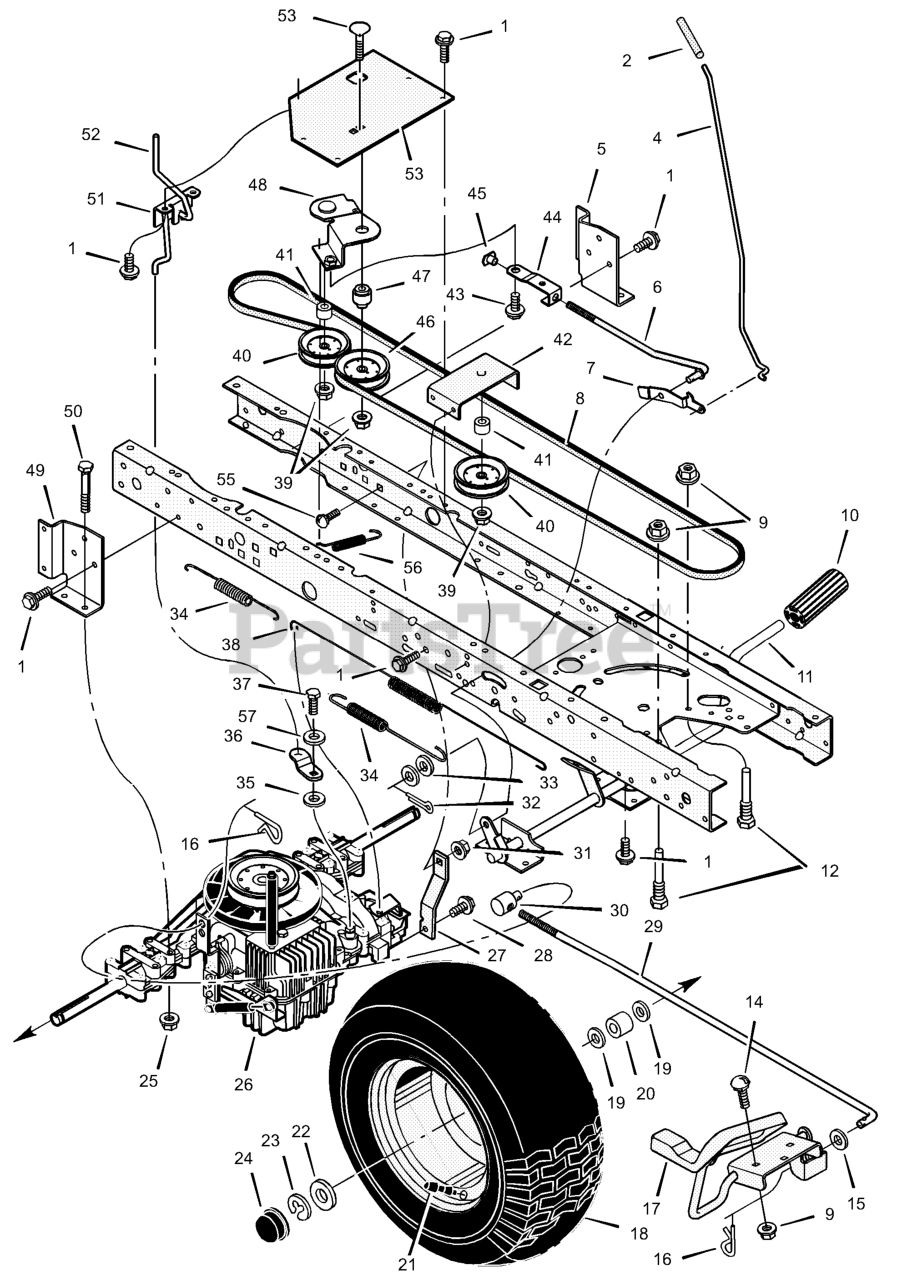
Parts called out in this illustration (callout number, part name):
2	Grip, Parking Brake
4	Rod, Parking Brake
5	Bracket, Left Transaxle
6	Rod, Clutch
7	Latch, Parking Brake
8	V-Belt, Drive
9	Nut, Flange
10	Pedal, Brake/Clutch
11	Assembly, Brake Pedal
12	Screw, Guide
14	Bolt, Carriage
16	Pin, Hair
17	Pedal Assembly, Hydro
18	Wheel & Tire Ass'y, Rear
20	Spacer
21	Stem, Valve
24	Cap, Hub
25	Nut, Centerlock
26	Transaxle **
27	Strap, Torque
29	Rod, Control
30	NUT, Adjusting, 1/2-13
31	Nut, Centerlock
32	Pin, Cotter
34	Spring, Extension
36	ARM, Disconnect
37	Capscrew
38	Spring, Brake
39	Locknut, Flange
40	Pulley, Idler
42	Bracket, Idler Assembly
43	Bolt, Shoulder
44	Link, Clutch
45	Nut, Tee
46	Pulley, Idler
47	Bushing, Pivot
48	Arm Assembly, Idler
49	Bracket, Right Transaxle
50	Bolt, Hex
51	Bracket, Disconnect
52	Rod, Disconnect
53	Bracket, Idler Pivot
54	Bolt, Carriage
55	Bolt, Carriage
56	Spring, Clutch
